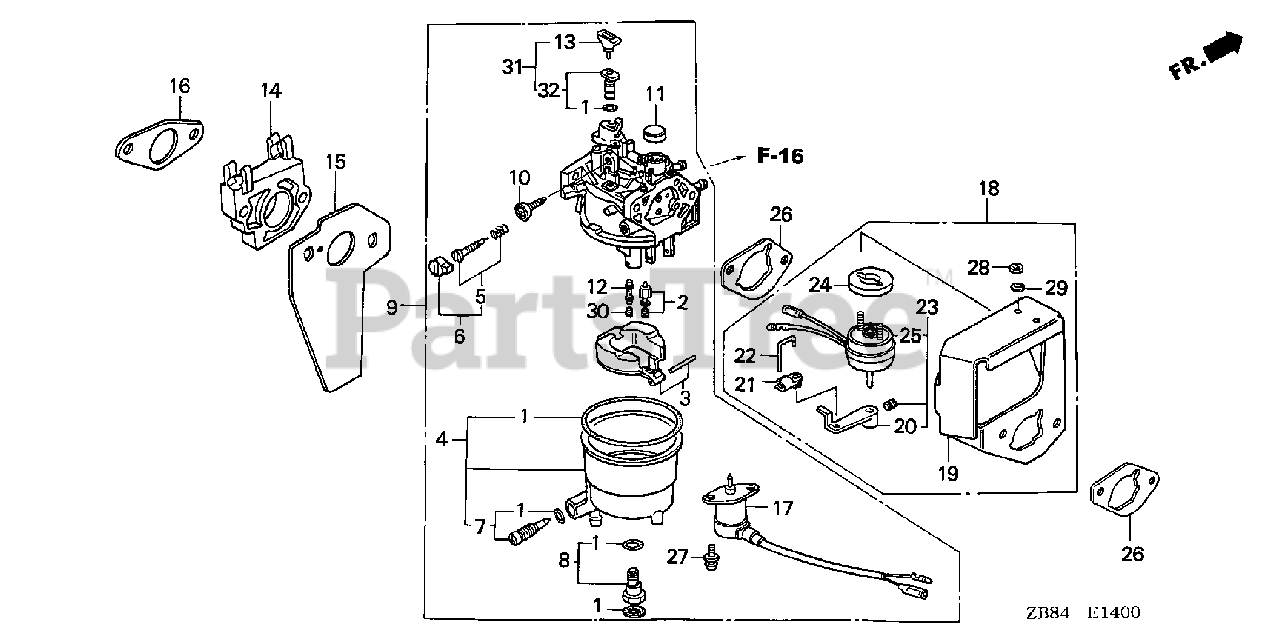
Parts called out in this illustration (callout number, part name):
1	GASKET SET
2	VALVE SET, FLOAT
4	CHAMBER SET, FLOAT
5	SCREW SET, PILOT
7	SCREW SET, DRAIN
9	CARBURETOR ASSY. (BE38A D)
10	SCREW, THROTTLE STOP
11	CAP, CHOKE DUST
12	NOZZLE, MAIN
14	INSULATOR, CARBURETOR
15	GASKET, CARBURETOR
16	GASKET, INSULATOR
17	VALVE ASSY., SOLENOID
18	STAY ASSY., SOLENOID
19	STAY, CHOKE SOLENOID
20	LEVER, CHOKE SOLENOID
21	JOINT, ROD
22	ROD, CHOKE SOLENOID
23	SOLENOID ASSY., CHOKE
24	SPACER, CHOKE SOLENOID
25	SOLENOID, ROTARY CHOKE
26	GASKET, AIR CLEANER
27	SCREW-WASHER (5X12)
28	NUT, HEX. (3MM)
29	WASHER, SPRING (3MM)
30	JET, MAIN (#92)
30	JET, MAIN (#95)
30	JET, MAIN (#98)
32	JET SET, PILOT (#38)
